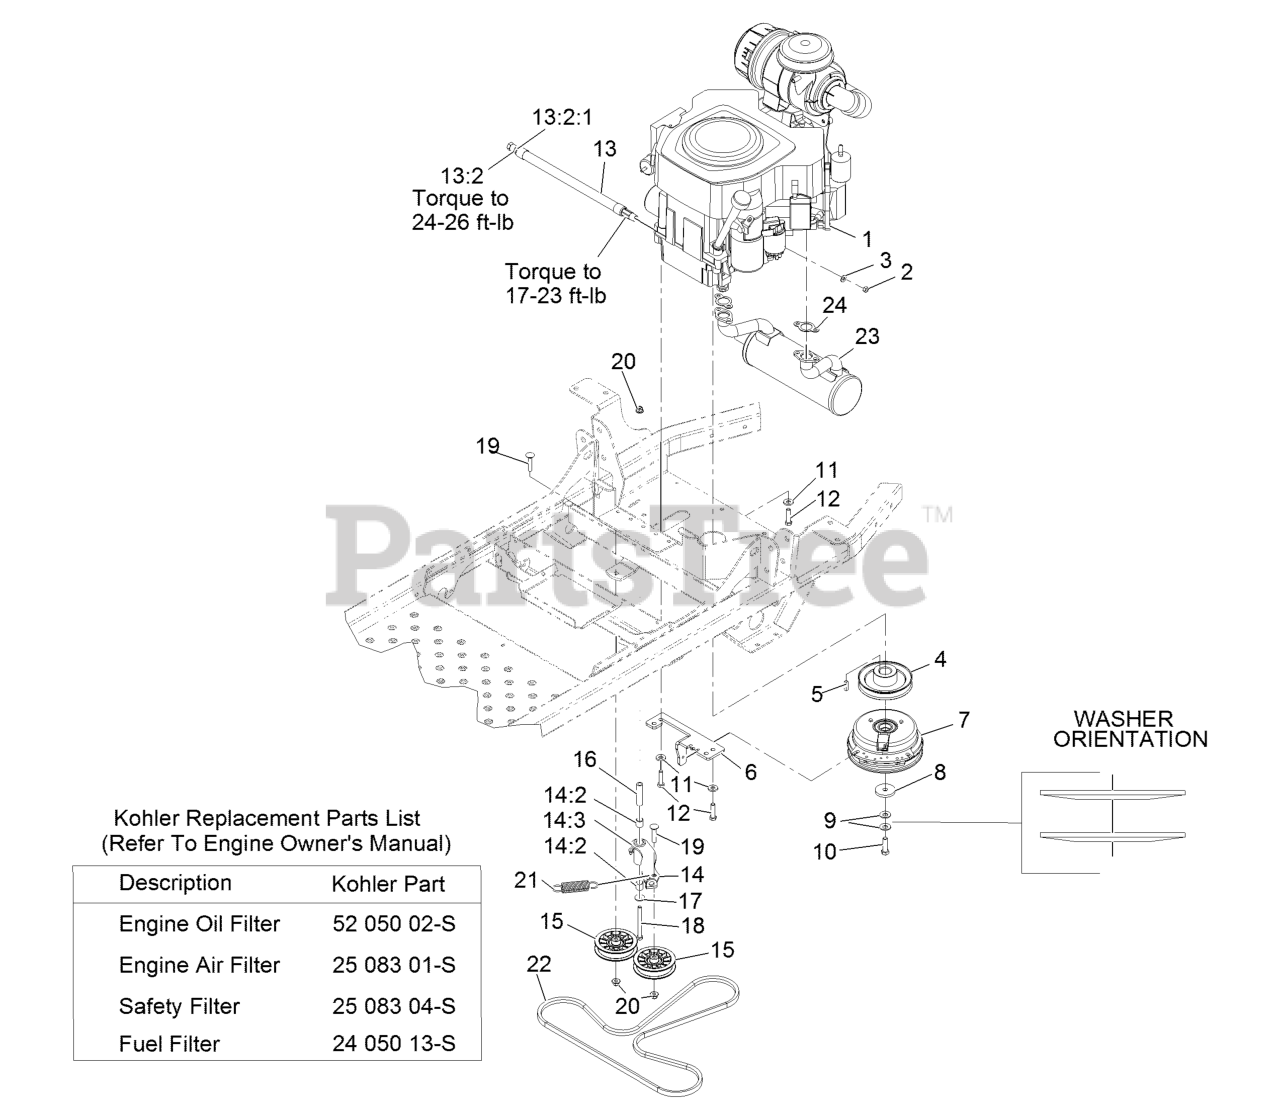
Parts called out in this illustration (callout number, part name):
1	Engine-Kohler
2	NUT-HEX
3	WASHER-FLAT
4	SHEAVE-PUMP, DRIVE
6	ANCHOR-CLUTCH
8	WASHER-CLUTCH
9	WASHER-SPRING
10	SCREW-HH 7/16-20 X 1 1/2 W/LOCTITE
11	WASHER-BELLEVILLE
12	SCREW-HWH
13	OIL DRAIN HOSE ASM
13:2	PLUG-HH
13:2:1	O-RING
14:2	SLEEVE-BEARING
14:3	FITTING-GREASE, 90 DEG
15	PULLEY-FLAT IDLER
16	BUSHING-PIVOT, IDLER
17	WASHER-FLAT
18	SCREW-CARR
19	SCREW-CARR
20	NUT-HF, NI
21	SPRING-EXTENSION
22	V-BELT
23	MUFFLER-KOHLER TWIN
24	GASKET-EXHAUST
